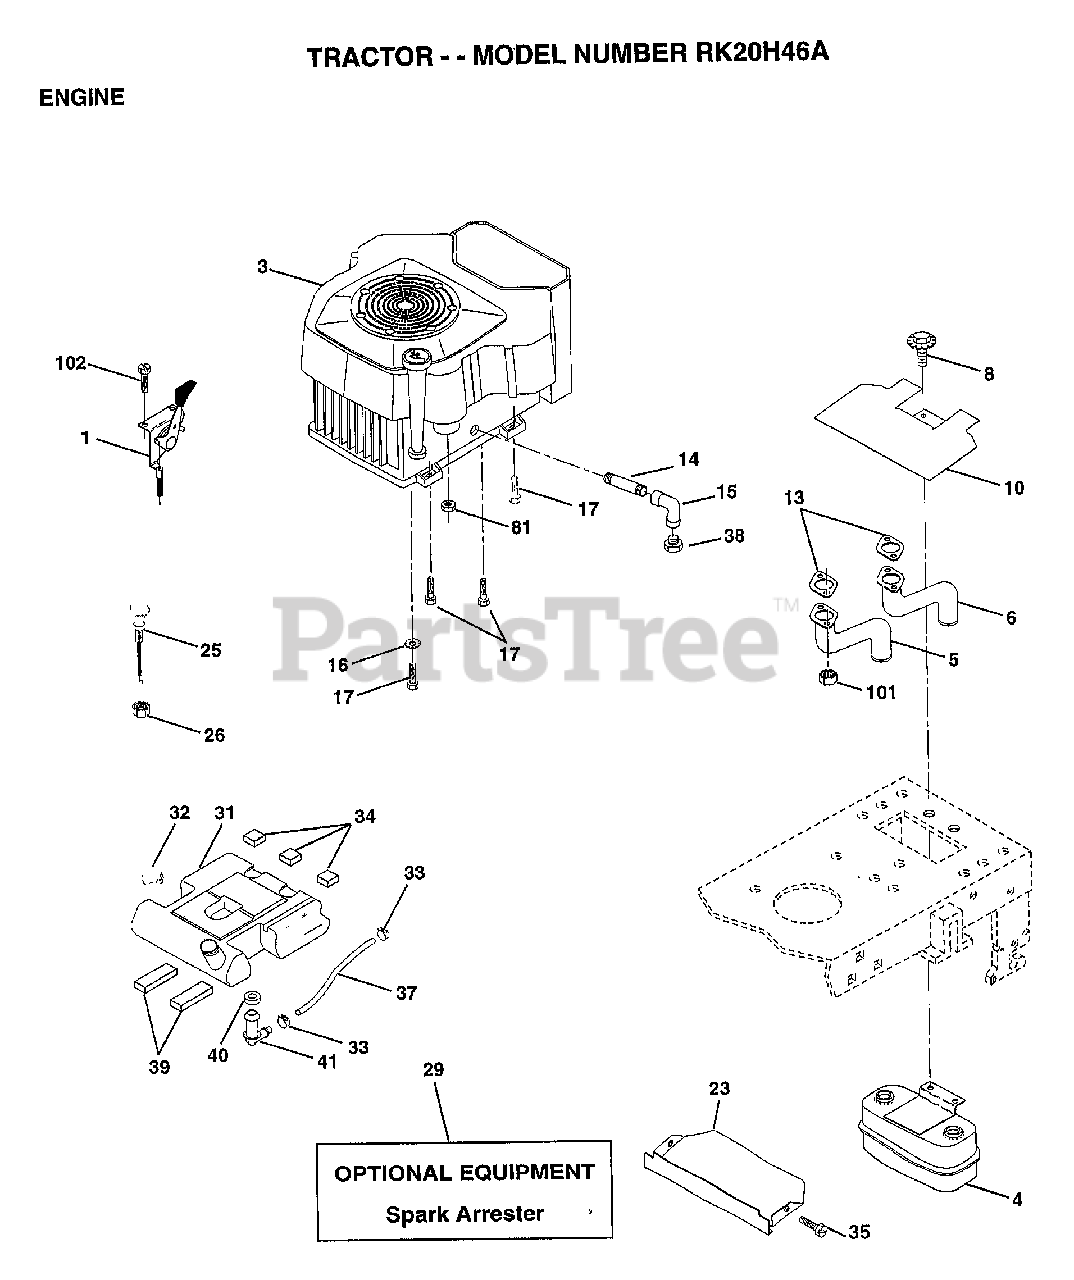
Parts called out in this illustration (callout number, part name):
4	MUFFLER.TW.LOTONE
5	PIPE-EXHAUST.LH
6	PIPE-EXHAUST.RH.
8	BOLT.5/16-18.UNC
10	SHIELD.HEAT.MUFF.
13	GASKET
14	PIPE NIPPLE LT
15	ELBOW
16	LOCKWASHER
17	SCREW LT
23	SHIELD.BRN/DBR.GD
25	CONTROL.CHOKE.37
26	"NUT,KEPS 3/8-24IM"
31	TANK FUEL REAR
32	CAP ASM FUEL
33	HOSE CLAMP
34	PAD-SPACER LT
35	SCREW
37	FUEL LINE T
39	PAD IDLER TI
40	BUSHING OUTLET T
41	STEM.TANK.FUEL
81	NUT
101	NUT FLANGE M8-125
102	SCREW LT
